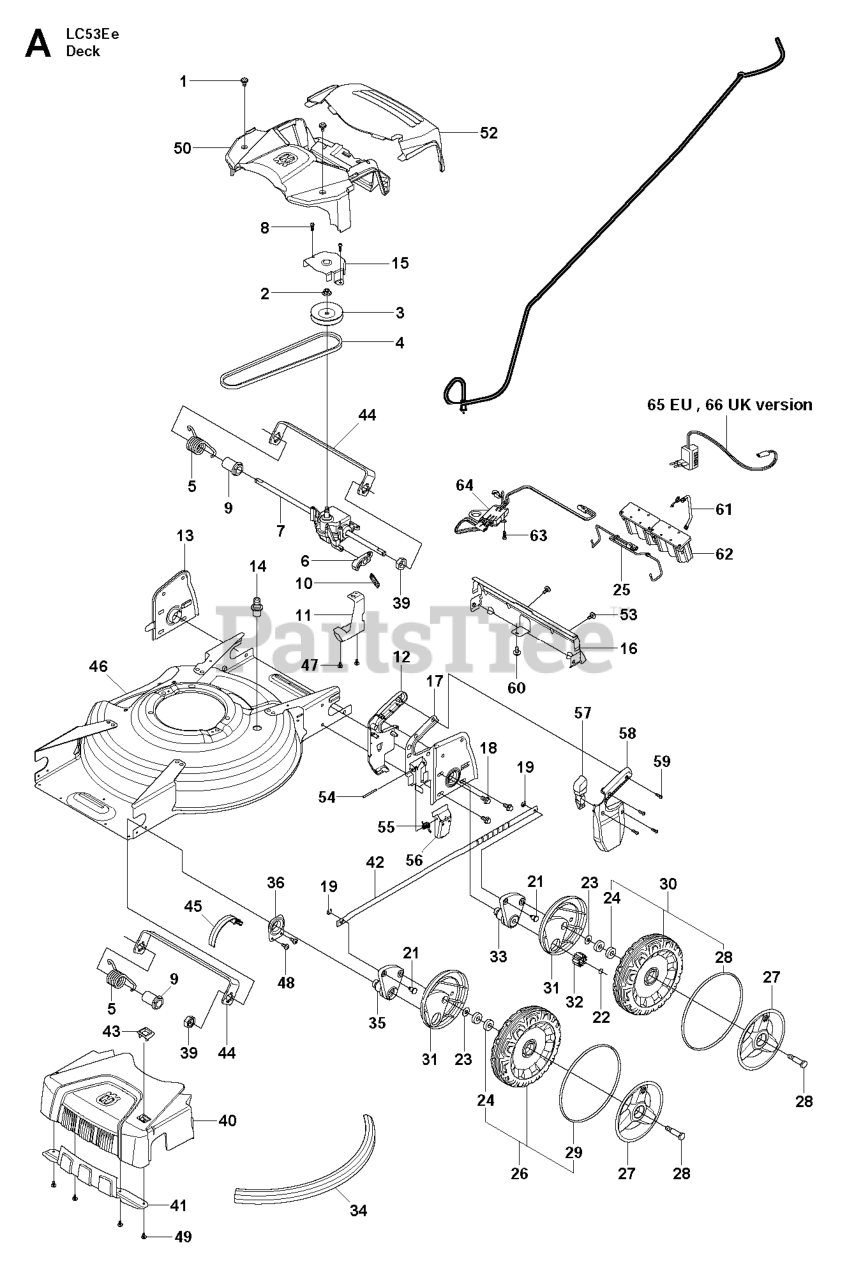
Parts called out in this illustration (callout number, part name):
1	SCREW ITXPANTT M5X10 ZPB (A00
8	SCREW ITXPANT T50X16 ZN/FE (A
19	FASTENER
24	BALL BEARING
47	SCREW ITXPANTT M5X10 ZPB (A00
48	SCREW ITXPANTT M5X10 ZPB (A00
49	SCREW ITXPANTT M5X10 ZPB (A00
53	SCREW ITXPANTT M5X10 ZPB (A00
59	SCREW ITXPANT T50X16 ZN/FE (A
60	SCREW ITXPANTT M5X10 ZPB (A00
63	SCREW ITXPANT T50X16 ZN/FE (A
